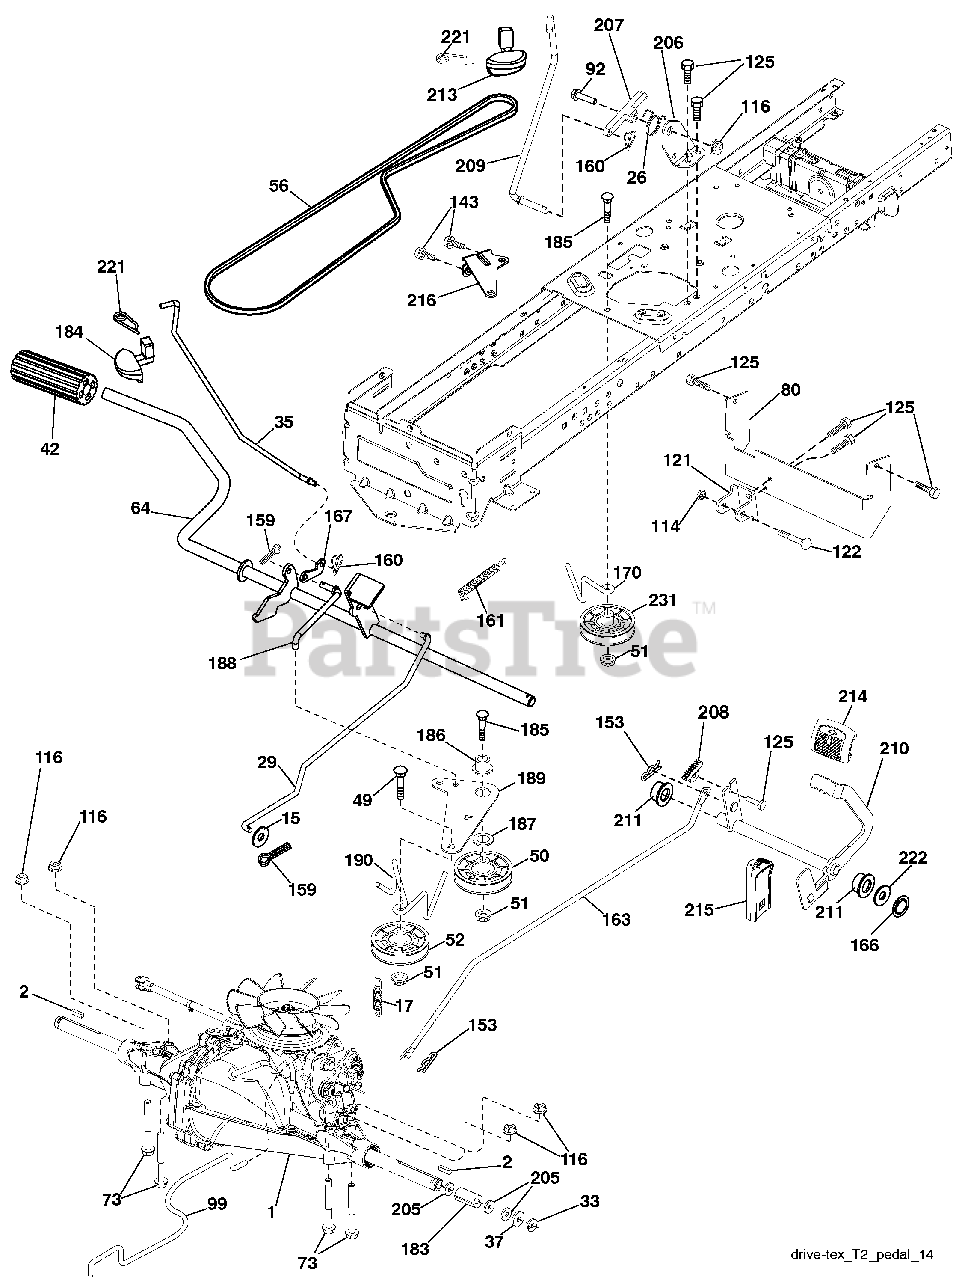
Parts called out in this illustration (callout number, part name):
2	Key
15	Washer 13/32 x 13/16 x 16 Ga.
17	Spring, Brake
26	Spring Return Cruise
29	Rod, Brake
33	Ring E
35	Rod, Brake, Park
37	Washer 25/32 x 1-1/4 x 16 Ga.
42	Cover, Foot Pedal
49	Bolt
50	Pulley Idler Flat
51	Lock Nut 3/8-16
52	Idler V-Groove 910" Offset
56	V-Belt, Drive
64	Shaft Asm. Pedal Brake Control
73	Bolt 5/16-18 Gr. 5
80	Strap Torque
92	Bolt Fin Hex 5/16-18 unc x 1.25
99	Rod Asm Bypass Spring
114	Nut Lock 5/16-18 unc
116	Nut Lock Hex Flange 5/16-18
121	Bracket Strap Torque
122	Bolt 5/16-18 x 2.50
125	Screw 5/16-18 x 3/4
143	Screw Thdrol 5/16-18 x 1/2
153	Retainer Spring
159	Pin Cotter 1/8 x 3/4
160	Retainer Clip
161	Spring, Return, Clutch
162	Adapter Transaxle
163	Rod Pedal Control
166	Nut Push .625
167	Latch Brake Parking
170	Keeper Belt Centerspan
183	Spacer Axle
184	Handle Parking Brake
185	Bolt
186	Spacer Retainer
187	Washer
188	Link Clutch Ground Drive
189	Bellcrank Ground Drive
190	Keeper Bellcrank Ground Drive
205	Washer 25/32 x 1-5/8 x 16 Ga.
206	Bracket Mount Latch Cruise
207	Latch Control Cruise
208	Gear Sector Control Cruise
209	Rod Control Cruise
210	Rockr Asm. Pdeal Control
211	Bearing Nylon
213	Knob control Cruise
214	Pad Pedal Forward
215	Pad Pedal Reverse
216	Bracket Pulley Idler
221	Retainer Spring Clip Handle
222	Washer 21/32 x 1-1/4 10 Ga.
231	Idler V-Groove 1.688
